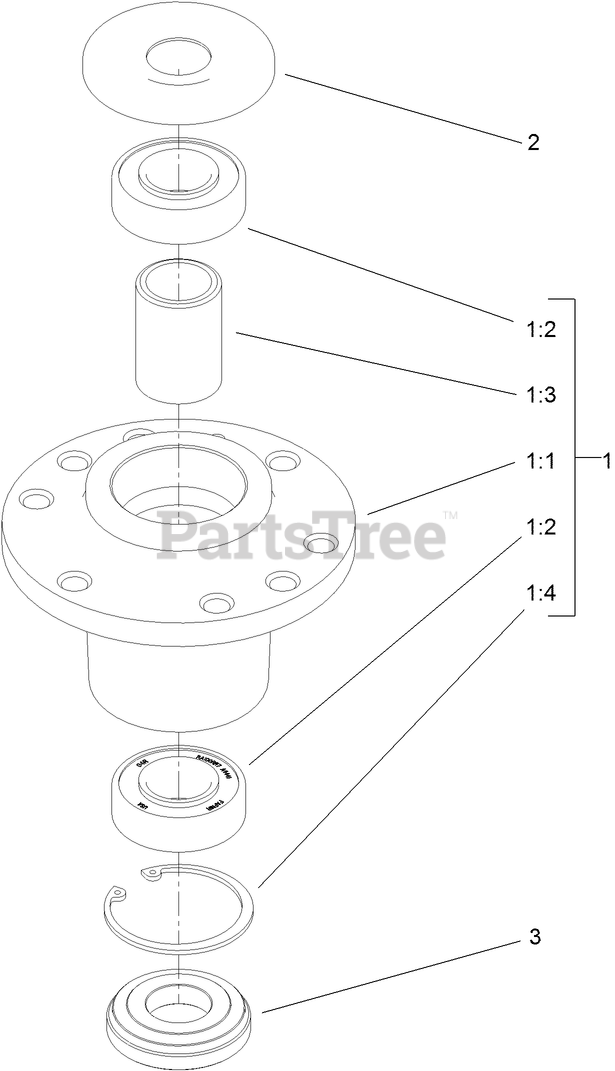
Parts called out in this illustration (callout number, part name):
1	CUTTER HOUSING ASM
1:1	HOUSING-SPINDLE
1:2	BEARING-JACKSHAFT
1:3	Spacer-Bearing
1:4	RING-SNAP
2	Guard-Bearing, Top
3	SPACER-GUARD, BOTTOM
